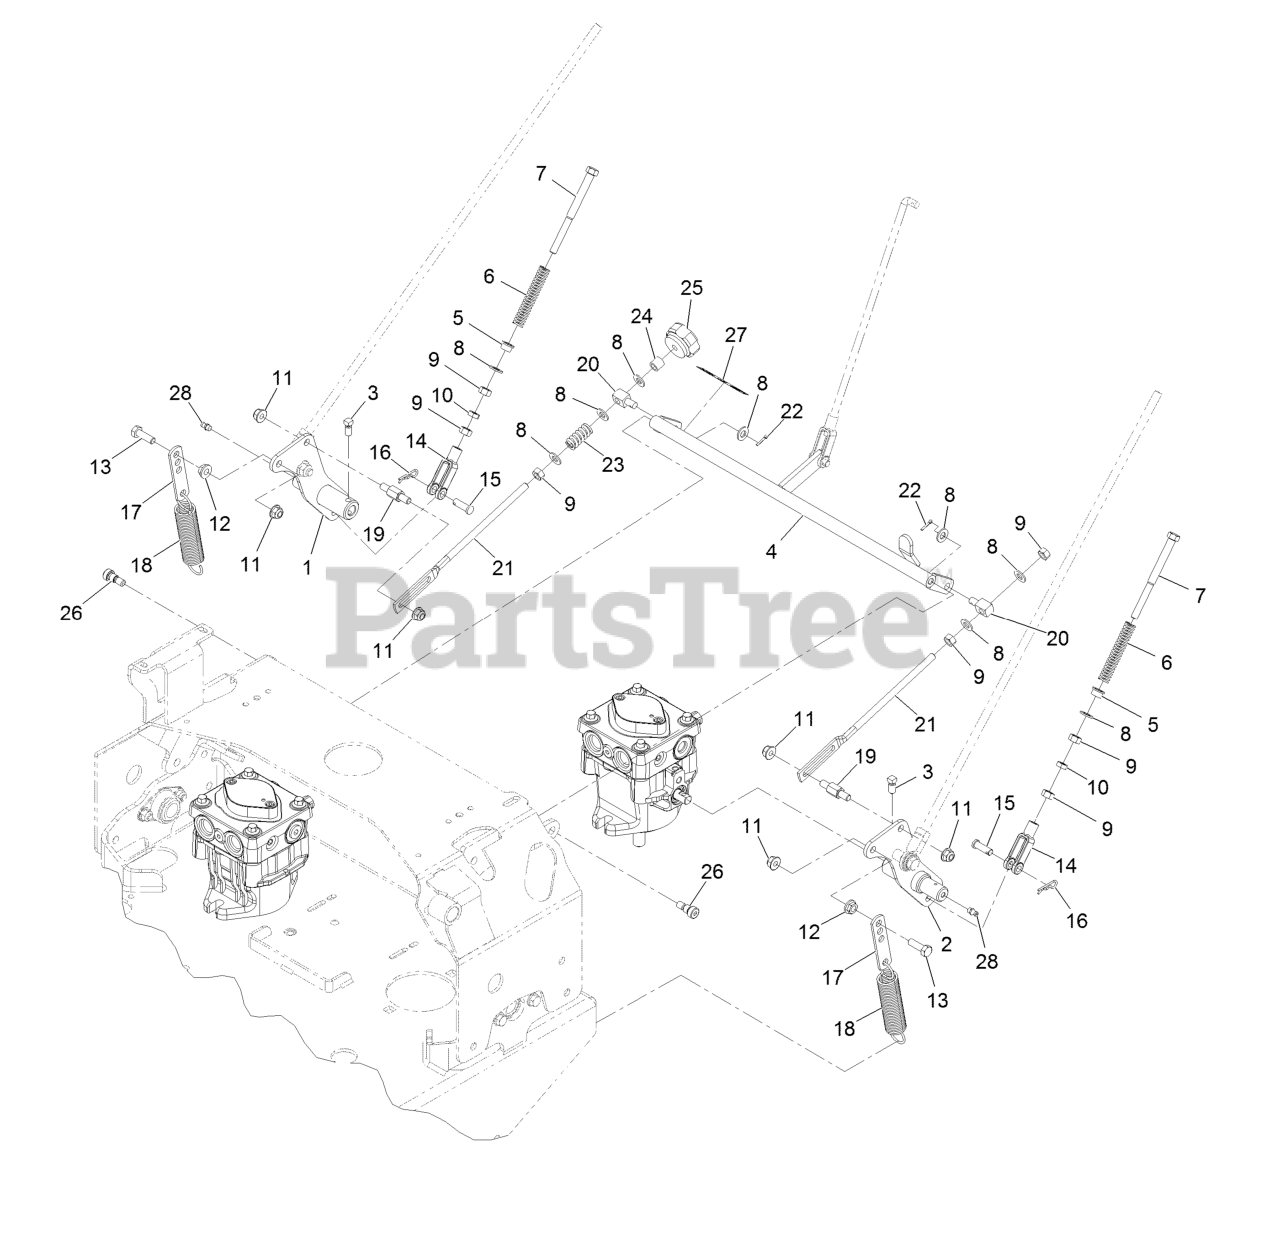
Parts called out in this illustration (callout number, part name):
1	Weld, Motion Control, Rt
2	Weld, Motion Control, Lt
3	Setscrew-5/16-18 X 5/8
4	Weld, Speed Control
5	Bushing-Flanged
6	Spring, Neutral Return
7	Bolt-Neutral Return
8	Washer-5/16 SAE
9	Nut-Hex 5/16-24
10	Nut-Jam 5/16-24
11	Nut-Nyloc 5/16-18 Flg
12	Nut-Whizlock 5/16-18
13	Screw-HH 5/16-18 X 1
14	Yoke-Adjustable
15	Pin-Clevis 5/16 X 1 49/64
16	Hairpin-Cotter
17	Tab-Spring, Extension
19	Pin, Motion Control
20	Swivel-Adjustable, Short
21	Link-Control, Speed
22	Pin-Cotter 3/32 X 1/2
23	Spring-Compression
25	Knob-Tracking
26	Screw-Sh 5/16-18 X 1 3/8
27	Decal-Tracking Adjustment
28	Zerk-1/4-28 Str
